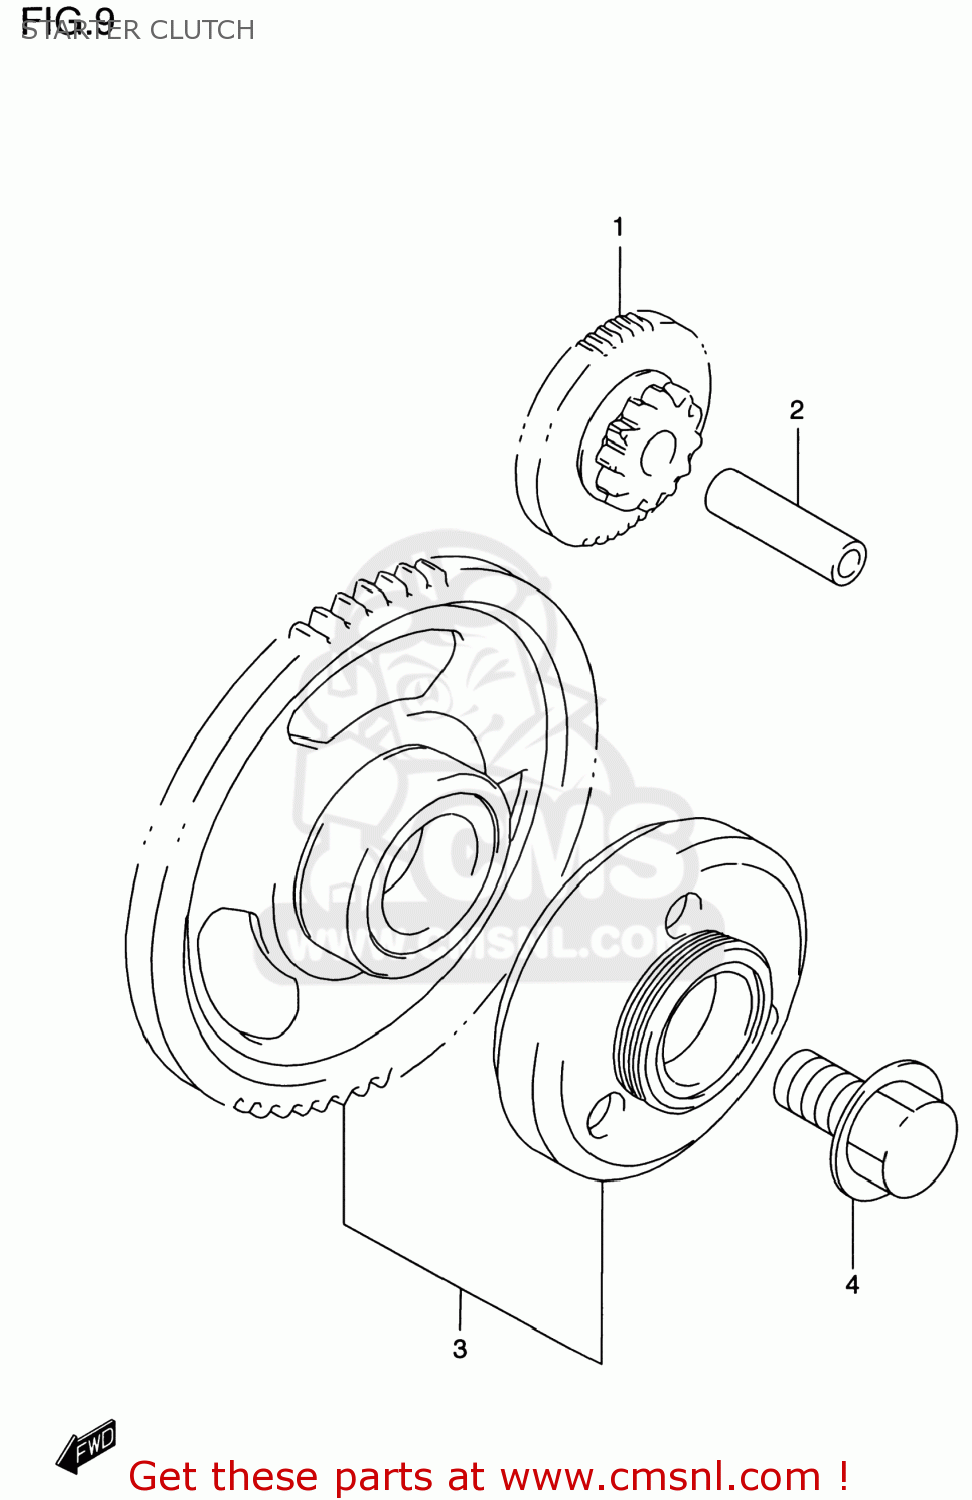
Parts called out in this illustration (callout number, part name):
1	GEAR,STARTER IDLE(NT:12,53)
2	PIN(7X11X42)
3	CLUTCH SET,STARTER
4	BOLT(14X21)
